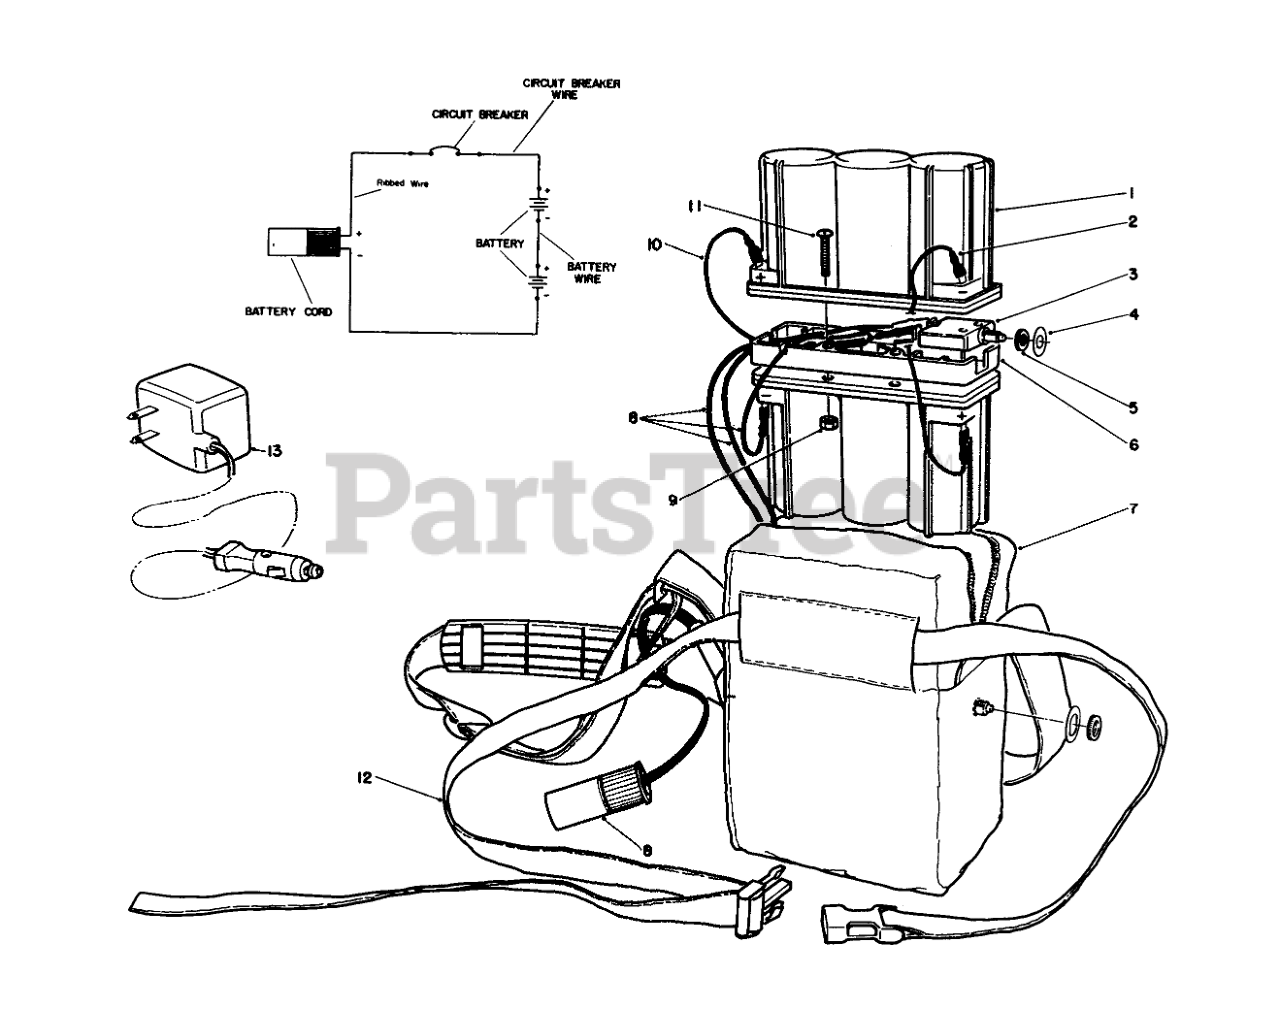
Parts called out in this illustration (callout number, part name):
1	BATTERY, 6 VOLT
2	WIRE ASSEMBLY-BATTERY
3	CKT BREAKER 15 AMP 125V
4	CIRCUIT BREAKER PLATE
5	KNURLED NUT
6	BATTERY SPACER
7	Pack-Soft
8	CORD-BATTERY PACK
9	NUT-HEX
10	WIRE ASSY-CIRCUIT BREAK
11	SCREW-PPH
12	BELT-WAIST
13	Charger 12 Volt
